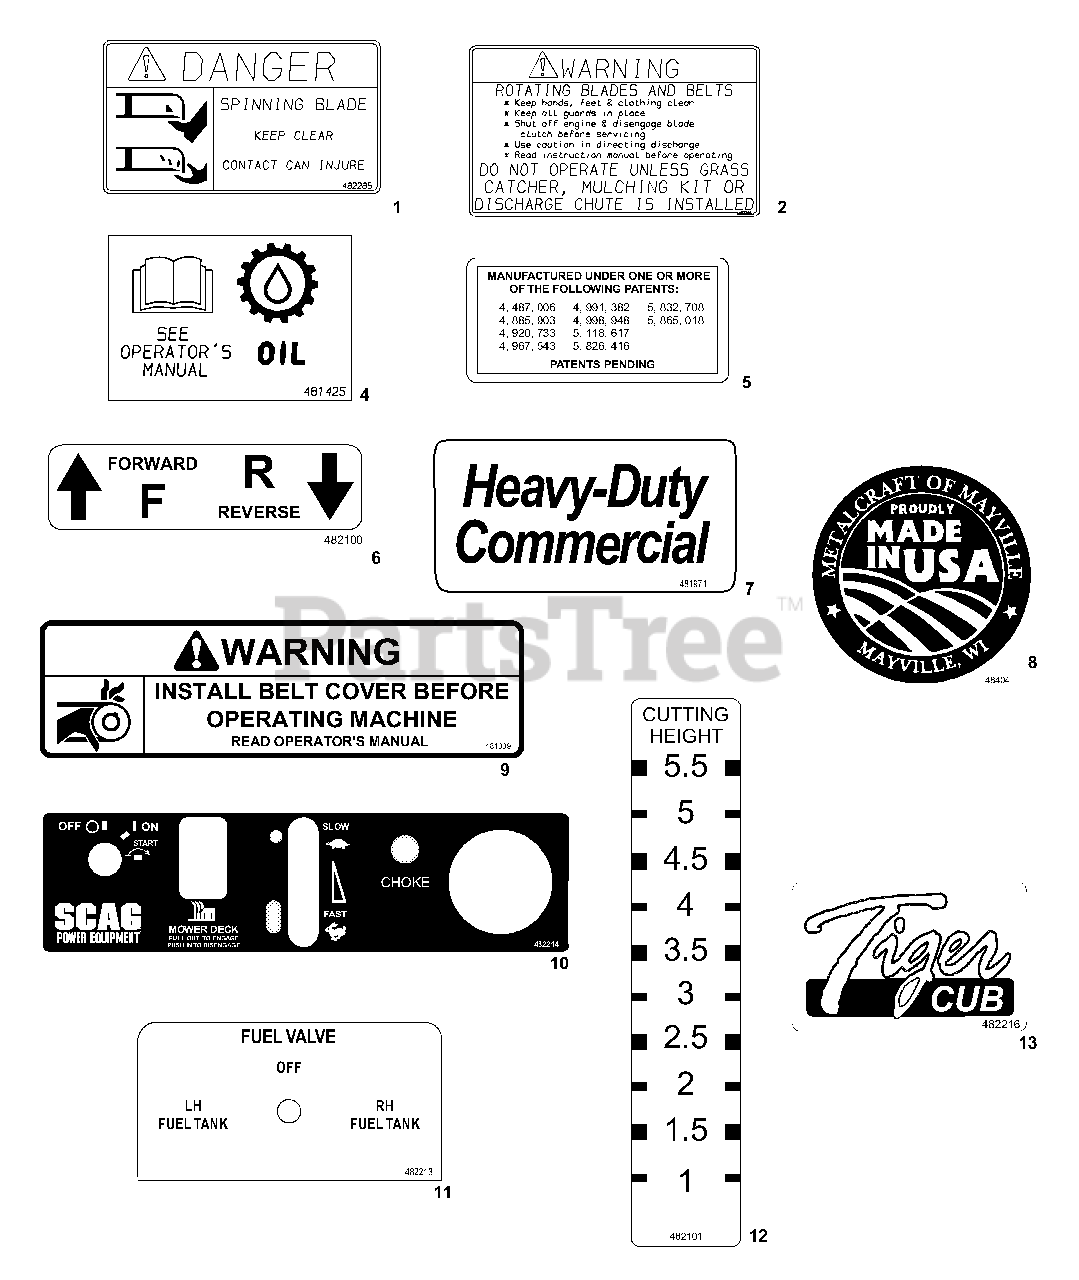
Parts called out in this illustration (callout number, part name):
1	Decal, Danger - Spining Blades
2	Decal, Warning - Rotating Blades
4	Decal, Oil
5	Decal, Patents
6	Decal, Traction Control
7	Decal, Heavy Duty Commercial
8	Decal, Metalcraft - Made in USA
9	Decal, Belt Cover
10	Decal, Instrument Panel
11	Decal, Fuel Valve Position
12	Decal, Cutting Height
13	Decal, Control Panel
